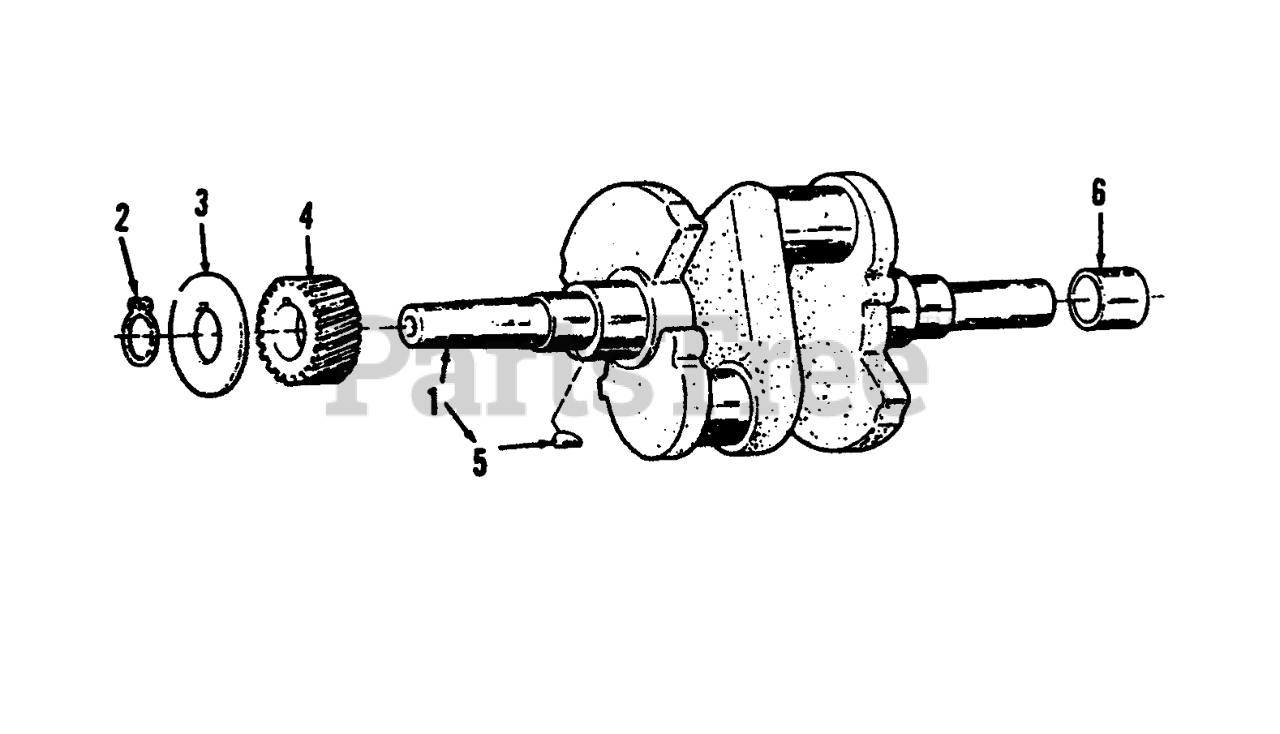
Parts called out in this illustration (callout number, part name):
1	CRANKSHAFT
2	Retaining Ring
3	Washer
4	Gear
5	Key
6	Cover-Valve
